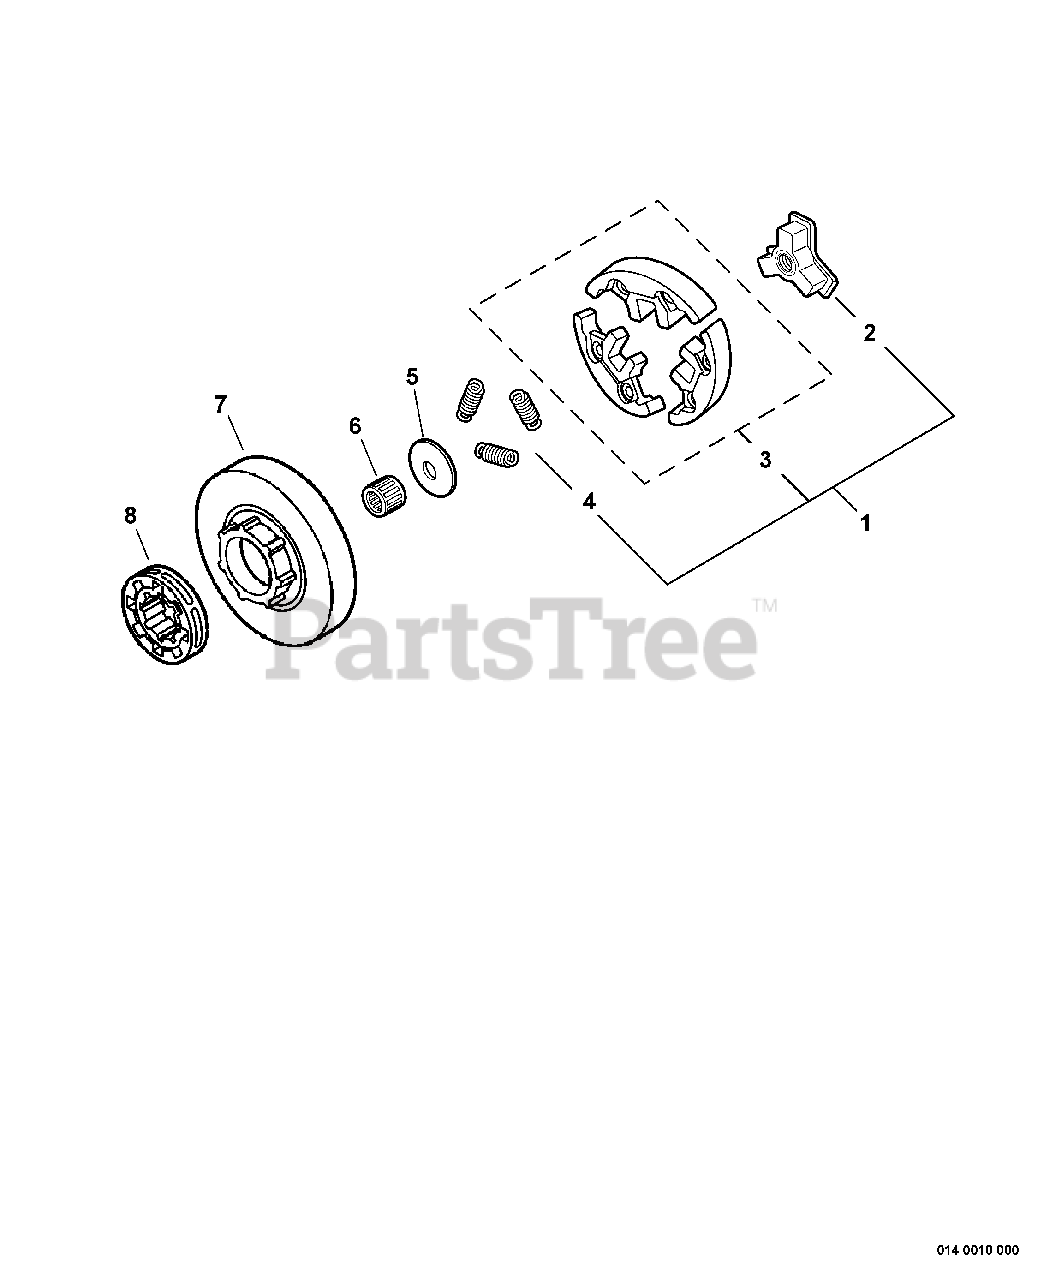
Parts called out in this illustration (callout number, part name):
1	CLUTCH ASSY
2	HUB, CLUTCH
3	SHOE SET, CLUTCH (3PCS)
4	SPRING, TENSION
5	PLATE, CLUTCH
6	BEARING, NEEDLE
7	DRUM, CLUTCH
8	SPROCKET, RIM 3/8"×7T
